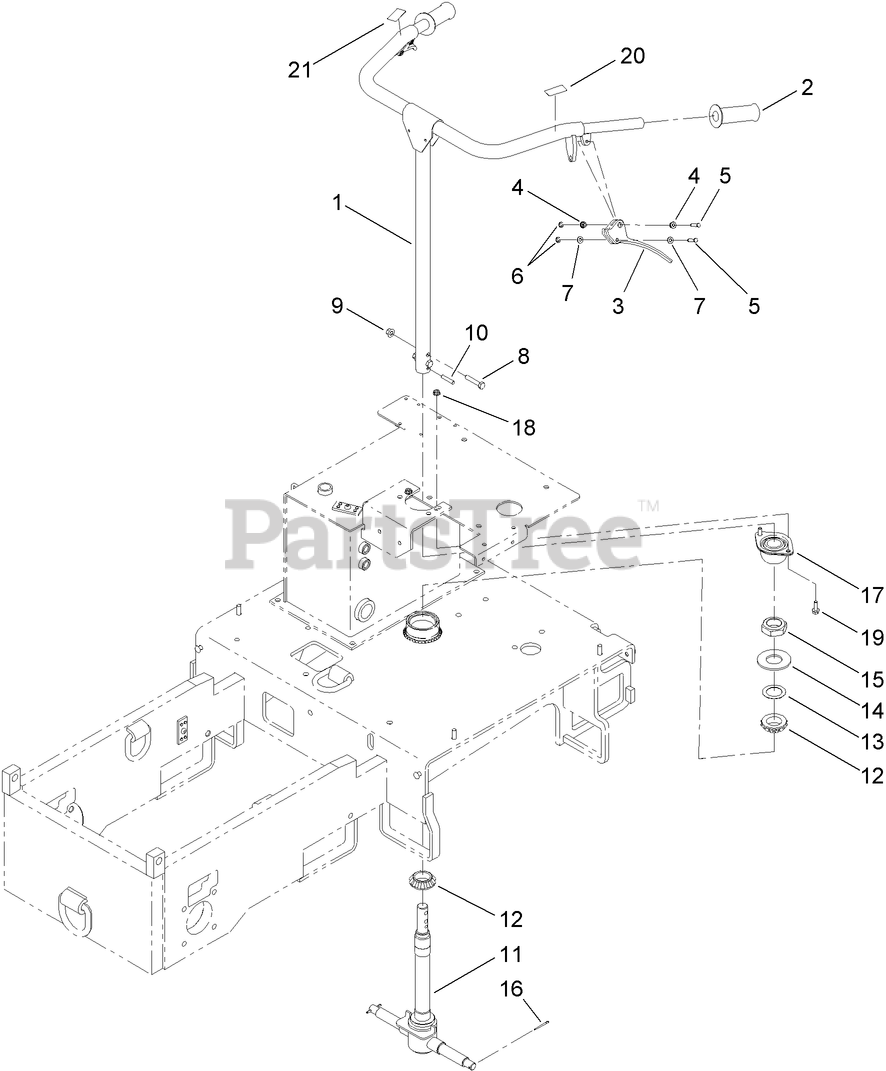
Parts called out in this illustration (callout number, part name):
1	HANDLE-STEERING
2	GRIP-HANDLE
3	HANDLE-CONTROL,
4	BUSHING-LEVER, CONTROL
5	PIN-CLEVIS
6	E-RING
7	WASHER-FLAT
8	SCREW-HH
9	NUT-HF
11	AXLE-STEERING
12	BEARING-ROLLER
13	WASHER-THRUST
14	PLATE-COVER, BEARING
16	PIN-COTTER
17	SPHERICAL BEARING ASM
18	NUT-FLANGE
19	SCREW-HHF
20	DECAL-REVERSE
21	DECAL-FORWARD
